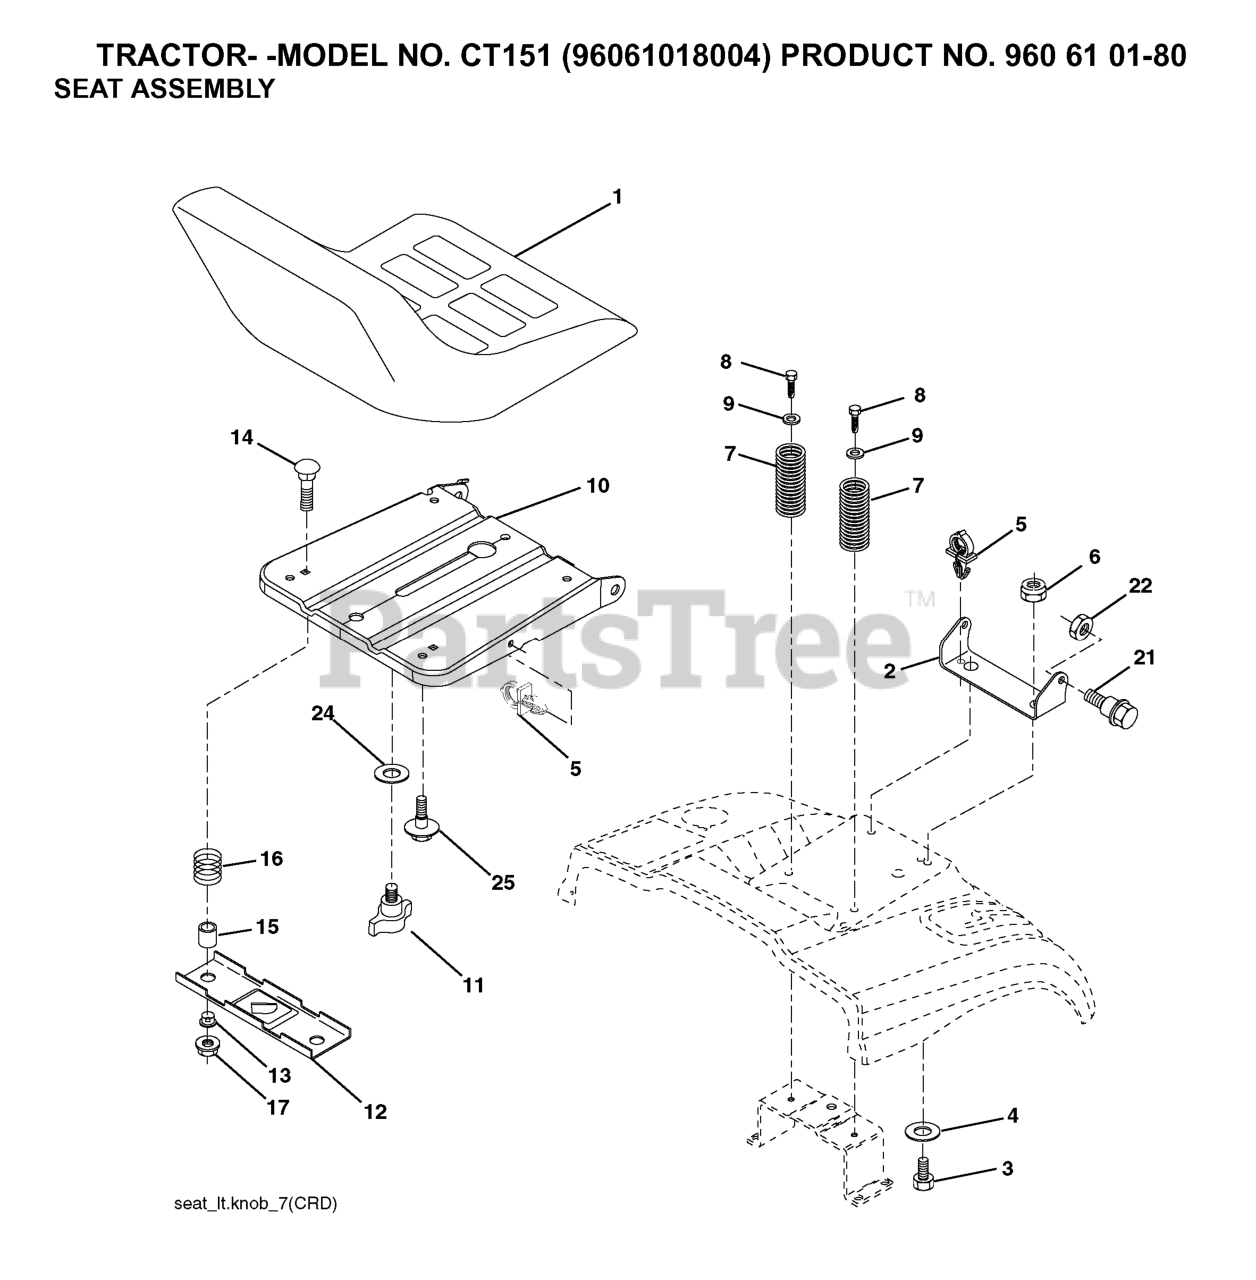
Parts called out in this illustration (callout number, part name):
1	RP SEAT
2	SEAT PIVOT BRKT
3	BOLT, HEX 3/8-16X1
6	NUT
7	SPRING COMPRESSION
8	SCREW 3/8-16X1
9	WASHER
10	PAN.ASM.SEAT.1SLOT
11	KNOB.SEAT.ADJ.WINGNUT
12	BRKT.MNTNG.SWITCH.SEAT.BLACK
14	BOLT.ROUND.HEAD.SQUARE.NECK
15	SPACER SPLIT 28X.96
17	NUT T
21	BOLT.SHOULDER.5/16-18
22	NUT.71038.31-18.HEX.NYLOCK
25	BOLT,SHOULD
